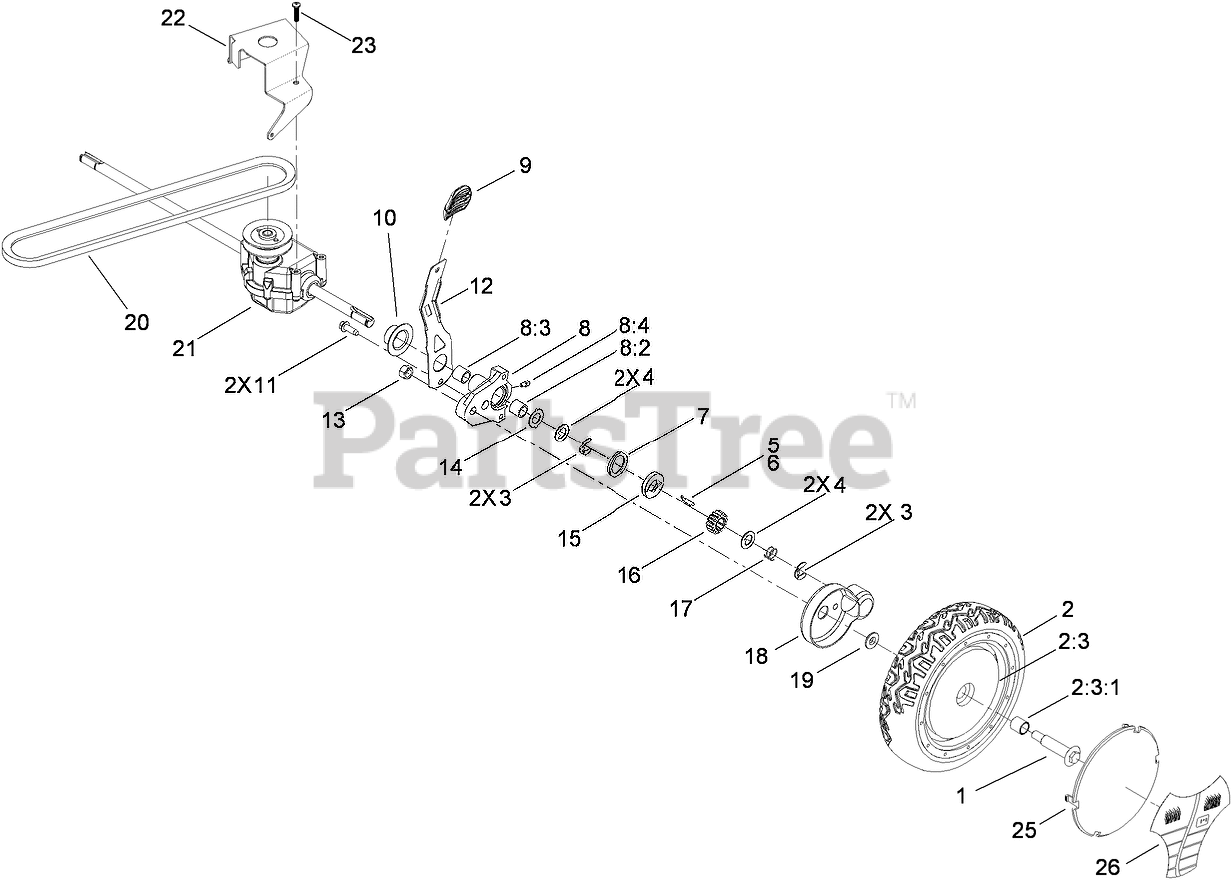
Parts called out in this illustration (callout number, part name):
1	BOLT-SHOULDER
2	WHEEL AND TIRE ASM (WITH GEAR)
2:3	WHEEL AND TIRE ASM
2:3:1	BUSHING
3	RING-CLIP, LOCKING
4	WASHER-THRUST, KEYED
5	KEY-ROCKING, RH
6	KEY-ROCKING, LH
7	RING-FRICTION
8	PIVOT ARM ASM
8:2	BUSHING
8:3	BUSHING
8:4	FITTING-GREASE
9	Knob-Lever, HOC
10	CAP-END
11	SCREW-HWHTF
12	ARM-SPRING
14	WASHER-ARM, PIVOT
15	WASHER-CLUTCH
16	GEAR-PINION
17	SPRING-COMPRESSION
18	COVER-WHEEL
19	SPACER-COVER, WHEEL
20	V-BELT
21	TRANSMISSION ASM
22	BRACKET-TRANSMISSION
23	SCREW-PLASTITE
25	COVER-WHEEL
26	LABEL-WHEEL, SMART
